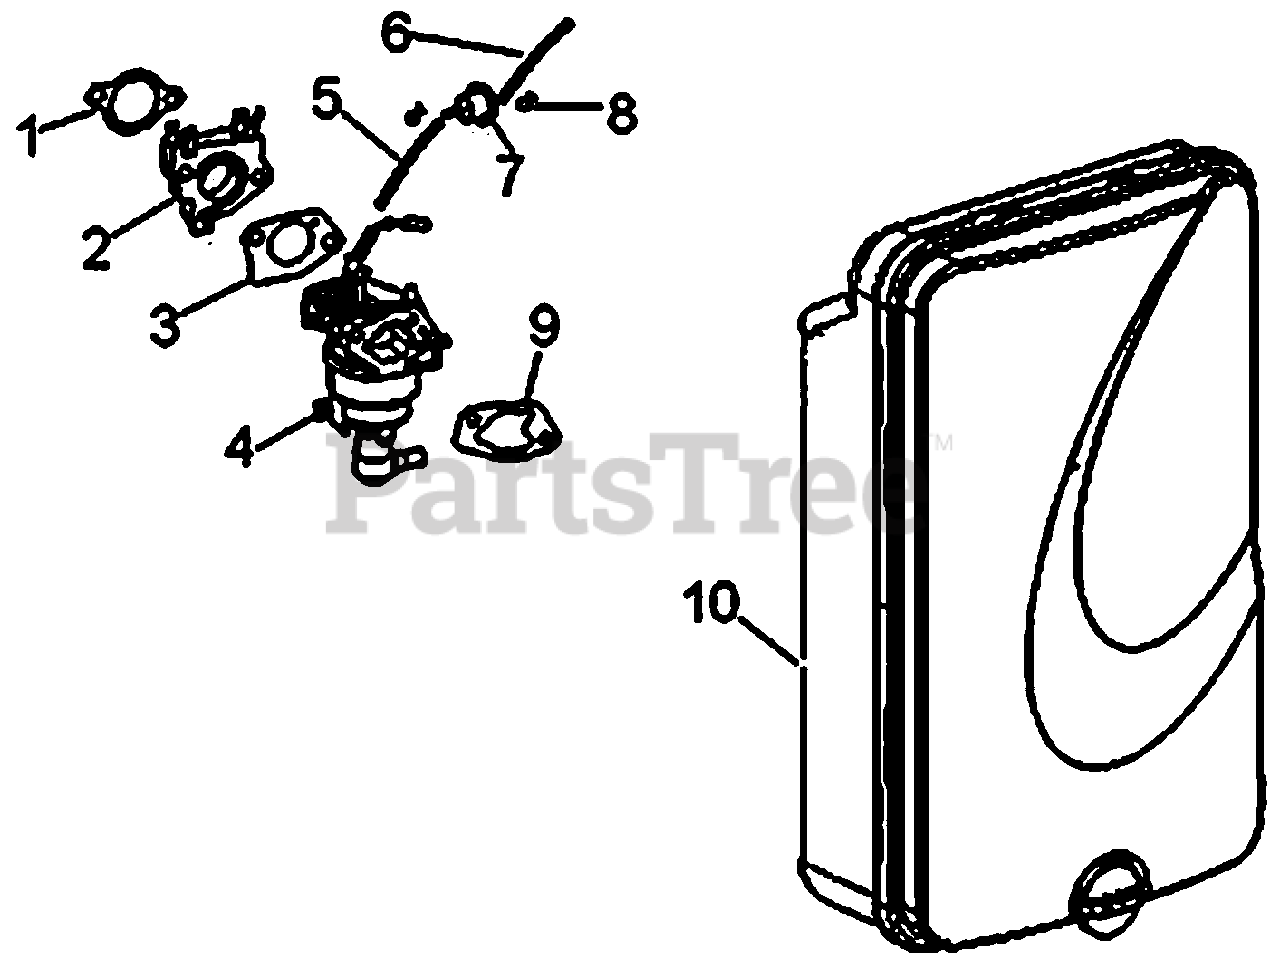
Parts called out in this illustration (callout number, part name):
1	GASKET, CARBURETOR
2	SPACER, CARBURETOR
3	GASKET, CARBURETOR
4	CARBURETOR ASSY.
5	TUBE, FUEL
6	TUBE, FUEL
9	GASKET, CARBURETOR
10	AIR CLEANER
